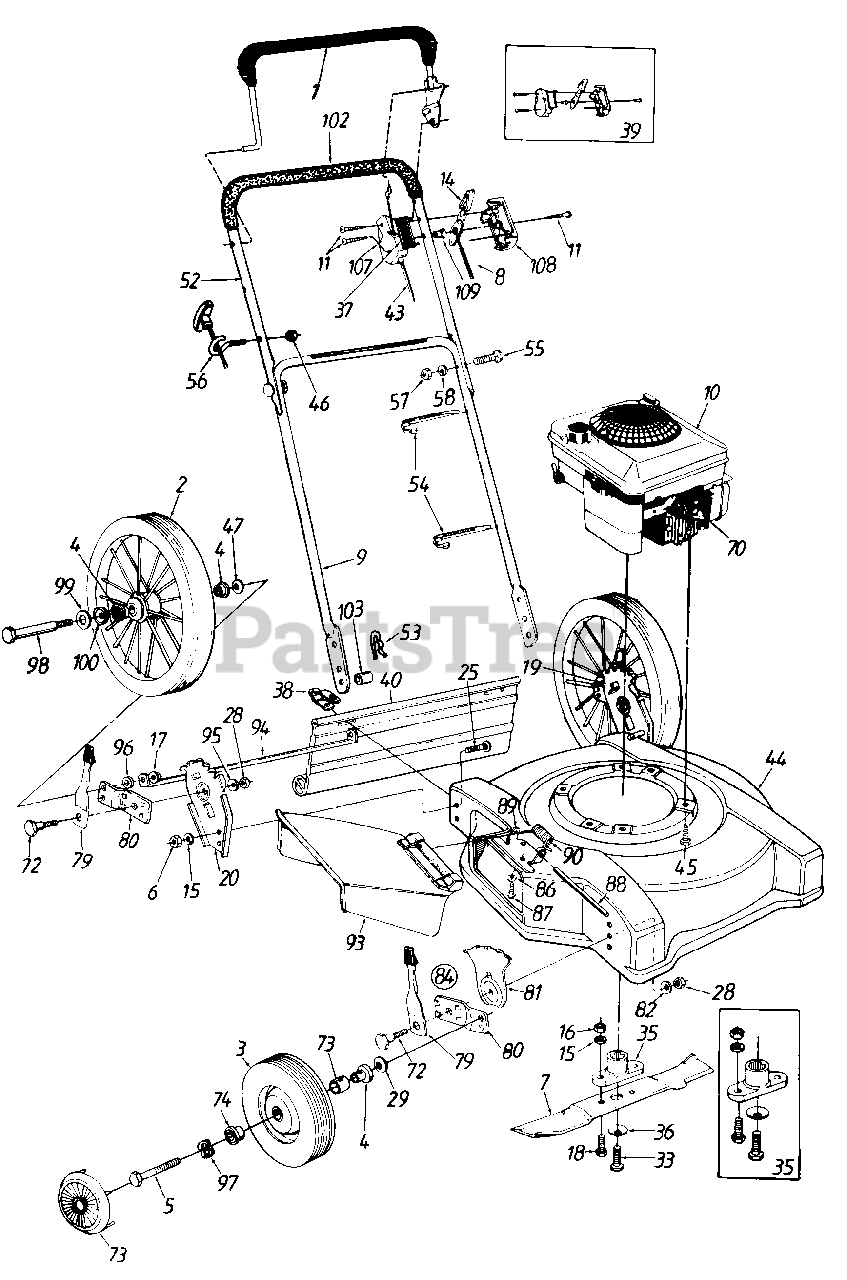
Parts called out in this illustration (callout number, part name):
1	Control Handle
2	16" Wheel Ass'y. (Steel)
3	Front Wheel Ass'y.
4	Bearing 1/2" I.D.
5	Front Axle Bolt
6	Hex Nut 3/8-24 Thd. (Gr. 8)
7	22" Blade
8	Throttle Control Wire 53"
9	Lower Handle
10	Engine
11	Truss Mach. Scr. #12 x 1.5" Lg.
14	Throttle Control Lever
15	L-Wash. 3/8" I.D.
16	Hex Nut 3/8-24 Thd.
17	Flange L-Nut 3/8-18 Thd.
18	Hex Bolt 3/8-24 x 1.0" Lg.
19	Wheel Brkt. Ass'y.-L.H.
20	Wheel Brkt. Ass'y.-R.H.
25	Ribbed Neck Bolt 3/8-24 x .80"
28	Hex Nut 3/8-16 Thd.
29	Bell-Wash. .400" 1 .D. x .88"
33	Hex Bolt 7/16-20 x 1.5" Lg.
35	Blade Adapter Kit
36	Bell-Wash. .46" I.D.
37	Throttle Label
38	Hinge Clip
39	Kit-Control Housing Comp.
40	Rear Flap Ass'y.
43	Control Cable-39"
44	22" DeckAss'y.
45	Hex Wash. Hd. TT-Tap Scr. 3/8-16 x 1.00" Lg.
46	Hex Nylon L-Nut 1/4-20 Thd.
47	Bell-Wash. .38" I.D. x .88"
53	Intern. Cot. Pin 5/16" Dia.
54	Cable Tie
55	Curved Carriage Bolt 5/16-18 x 1.38" Lg.
57	Hex Nut 5/16-18 Thd.
58	L-Wash. 5/16" I.D.
70	Spark Plug Boot
72	Shoulder Bolt .50" Dia.
74	Ball Bearing 3/8" I.D.
79	Spring Lever Ass'y. w/Knob
81	HeightAdj. Plate
82	Bell-Wash. .39" I.D. x 1.38"
84	Front Height Adj. Ass'y. Comp.-R.H.
86	Bell-Wash. .285" I.D. x .75"
87	Hex Wash. Hd. Tap Scr. 1/4-20 x .5" Lg.
88	Hinge Pin
89	Adapter Plate
90	Torsion Spring
93	Chute Deflector Ass'y. Comp.
96	Spacer .503" I.D. x .75"
97	WaveWasher .53" I.D.
98	RearAxle Bolt
99	Fl-Wash. .51 " I.D. x 1.372"
100	Spr. Wash. .5" I.D. x 1.0"
102	Foam Grip
107	Clutch Panel Half
108	Control Panel Half
109	Control Disc Pin
